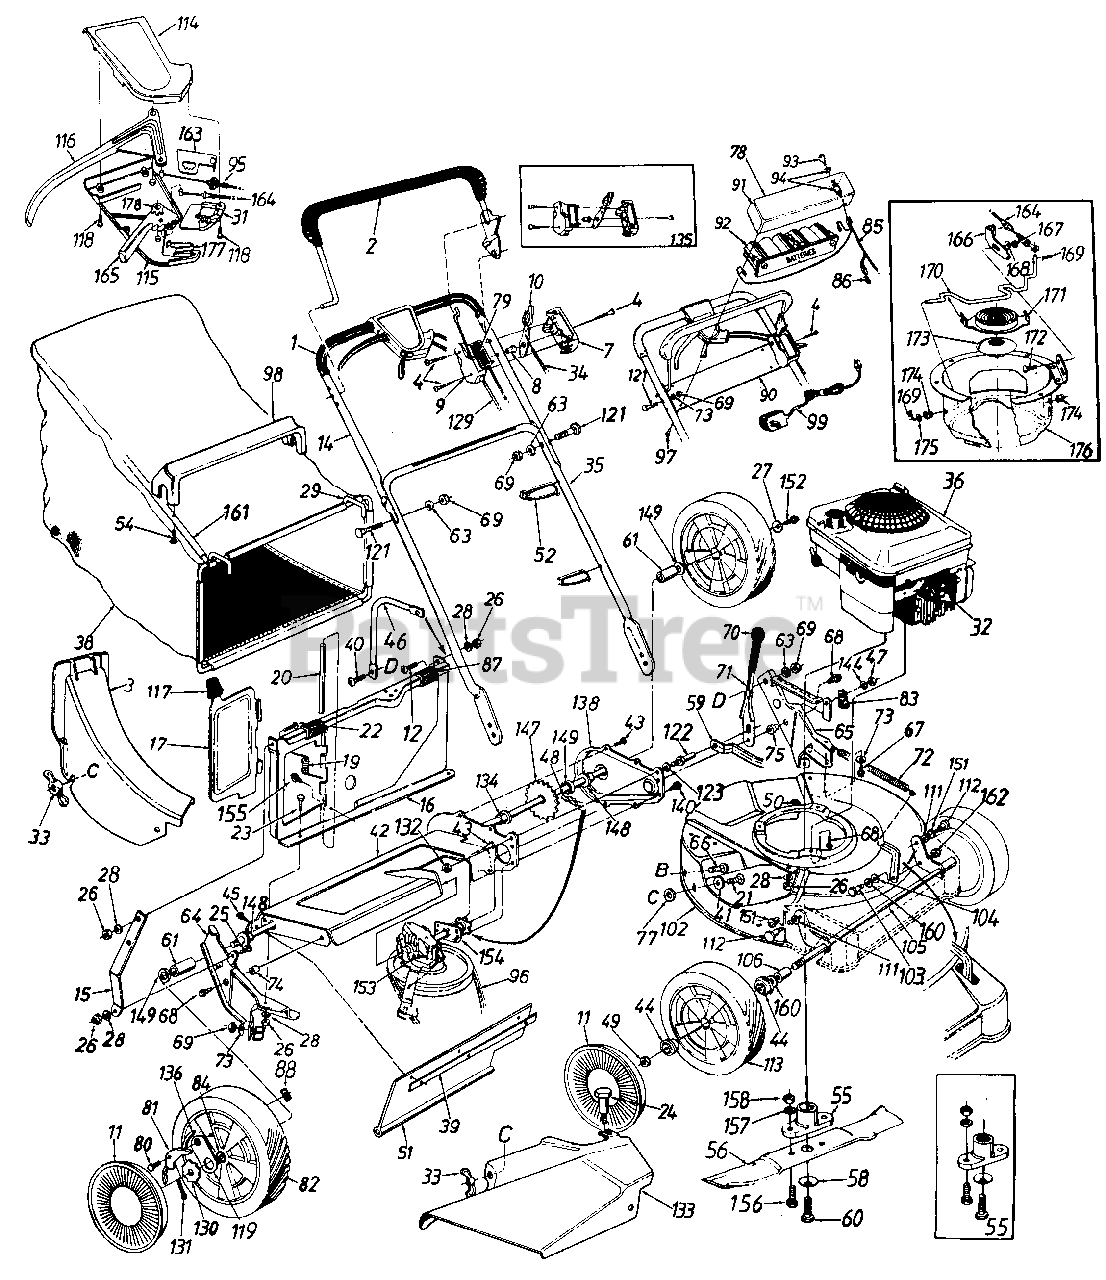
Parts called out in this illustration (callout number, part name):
1	GRIP-FOAM
3	CHUTE ASSY BLACK
4	SCREW-TRUSS MACH
7	PANEL HALF-CONTROL
8	PIN-CONTROL DISC
9	PANEL HALF-CLUTCH
10	LEVER-THROTTLE CONT-REV
11	HUB CAP
12	SCREW-TRUSS MACH
14	HANDLE-UPPER
19	SPRING-TORSION
21	BOLT-CARRIAGE 1/4-20 X .62
22	SCREW-TRUSS MACH
23	SCREW-HEX 1/4-20 X .50
24	SCREW-SHLD
25	SCREW-HEX 1/4-20 C .62
26	NUT-HEX 1/4-20
27	WASHER-SPRING BELL
28	LOCK WASHER 1/4 DIA
31	COVER-SP CONTROL
32	INSULATOR-SPARK PLUG
33	NUT-WING
34	WIRE-THROTTLE
35	HANDLE-LOWER PAINTED
38	BAG-GRASS-BLACK
39	STRIP-RETAINING
40	SCREW-TRUSS MACH 5/16-18 X .75
41	WASHER-FL-.344 ID X .62 OD X .033
44	BEARING-BALL
45	SCREW-HEX WASH HD
46	ARM-CATCHER SUPPORT
47	NUT-HEX LOCK 3/8-24
48	#48 CHAIN 1/2 PITCH
49	NUT-HEX INS L-1/2-20
52	TIE-CABLE
54	SCREW-HEX AB-TAP
55	KIT-BLADE ADAPTER-SPLINED
56	BLADE-21IN
58	WASHER-BELL
59	ARM-HGT ADJ CONNECT
60	SCREW-HEX 7/16-20 X 1.50
61	SPACER-.513 ID X .703 OD X .69
63	WASHER-LOCK-5/16
64	BRACKET ASSY-HDLE-RH
65	BRACKET ASSY-HDLE-LH
66	BOLT-CARRIAGE 5/16-18 X .62
67	SCREW-HEX WASH HD 5/16-18X1/2
68	SCREW-HEX R
69	NUT-HEX 5/16-18
71	LEVER-HGT ADJ
72	SPRING-EXTENSION
73	WASHER-BELL .337 X .867 X .057
74	SPACER
75	SPACER-SHLD .500 X .100
77	RETAINER-BOLT 1/4X.50 OD
80	SCREW-SHLD .342 DIA X .268
81	PAWL
82	WHEEL ASSY W/TIRE
85	WIRE HARNESS
86	PLUG
87	CLIP-PANEL BAG
88	NUT-FLAT WELD 1/4 X 20
90	TRAY-BATTERY-LOWER
91	TRAY-BATTERY-UPPER
92	BATTERY PACK
93	KEY-IGN (SET OF TWO)
94	SWITCH-KEY
95	CABLE-CLUTCH
96	BELT-V 3/8 X 31.0
97	SCREW-TAP .215 X 1
98	HANDLE-BAG-BLACK
99	CHARGER-BATTERY
102	DECK ASSEMBLY-21IN
103	SCREW-SHLD .500 DIA X .295
104	WASHER-BELL .505 ID X 1.00 OD
105	AXLE ASSY
111	WASHER-INTERN L 3/8 X.56 OD X .018
112	SCREW-SHLD
113	WHEEL ASSY W/TIRE E
114	COVER-SP CONTROL-UPR
115	COVER-SP CONTROL-LWR
116	LEVER-CONTROL
117	KNOB
118	SCREW-FL C-SUNK AB
119	PLATE-PAWL
121	BOLT-CARRIAGE-CURV 5/16-18 X 1.38
122	PIN-SHLD 3/8-24X1.43 LG
123	WASHER-LOCK-3/8
129	CABLE-CONTROL
130	RATCHET
131	PIN-COTTER-1/8 DIA X 1.00
132	NUT-HEX JAM 3/8X24
133	DEFLECTOR-SIDE CHUTE
134	BEARING-HEX FLANGE
135	KIT-THROTTLE CONTROL
136	SPRING-NYLON
144	WASHER-FL-.385 ID X .87 OD X .06
147	SHAFT ASSY-REAR
148	BEARING-HEX FLANGE .506 ID
149	WASHER-FL-.531 X .930 OD X .050
151	BEARING-NYLINER
152	SCREW-1/4-20 X .62
153	TRANSMISSION-COMP
154	BEARING-CUP HEX
155	SCREW-HEX B-TAP #10 X .38
156	SCREW-HEX 3/8-24 X 1 LG
157	WASHER-LOCK-3/8
158	NUT-HEX 3/8-24
160	WASHER-FL-.510 ID X .75 OD X .033
162	NUT-HEX CENTER L-JAM
163	BRACKET-CABLE
164	CABLE-SPEED CONTROL
165	LEVER-6 SPEED SHIFT
168	NUT-HEX LOCK 1/4 X 20
169	PIN-COTTER-3/32 DIA X .75
170	ROD-SHIFT-LH
171	PULLEY ASSY-MOVEABLE
172	BOLT-CARRIAGE 1/4-20 X .50
173	PULLEY-MOVABLE
174	BUSHING-FLANGED
175	WASHER-FL
176	BRACKET ASSY-MTG
177	SPRING-SHIFT LEVER
178	INSERT-3 TOOTH RACK
